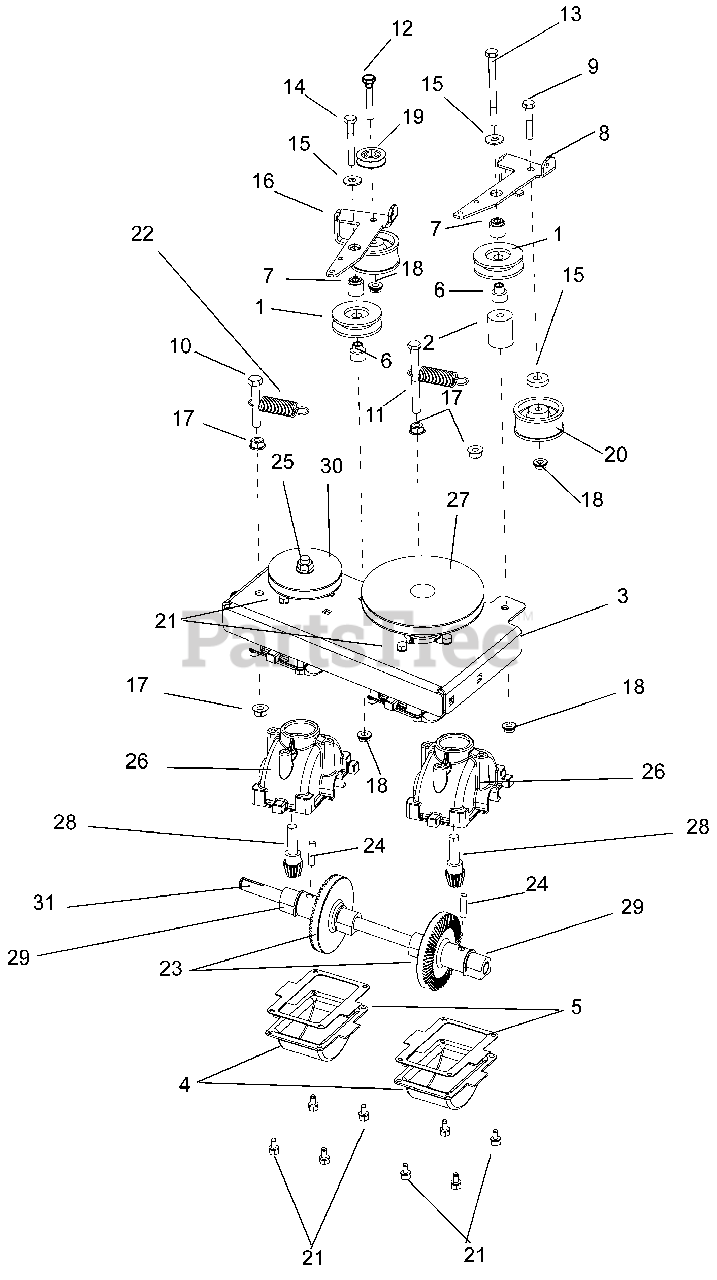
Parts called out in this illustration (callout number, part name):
1	Idler, 3L Front Side .38 x 1.875
2	Spacer, Reverse Idler
3	Plate, Transmission Mount
4	Sump, Gearbox
5	Gasket, Transmission
6	Spacer, Idler Pulley
7	Spacer .390 x .75 x .189
8	Bracket, Transmission Idler Arm
9	Bolt, Hex .25-20 x 1.50
10	Bolt, Hex .31-18 x 2.00
11	Bolt, Hex .31-18 x 3.50 Grade 5
12	Bolt, Hex .25-20 x 1.75
13	Bolt, Hex .25-20 x 3.25
14	Bolt, Hex .25-20 x 2.00
15	Washer, Flat Steel .312 x .734 x .065
16	Washer, Flat Steel .38 x .87 x .179
17	Nut, Spin Lock Flange .312-18
18	Nut, Locking Top Flange .25-20
19	Pulley, Cable
20	Pulley, Idler .25 x 1.87 x .97
21	Screw, Tapping 10-24 x .375 Pre-Coat
22	Spring, Tension .063 x .625 x 2.50
23	Gear, Bevel (CU Infiltrate)
24	Pin, .250 x 1.0 Spring
25	Nut, Top-Locking Flange .38-16
26	Housing, WAW Gearbox
27	Pulley, Reverse Input
28	Pinion, Gearbox Input
29	Bushing, Transmission Output Shaft
30	Pulley, Transmission Input
31	Kit, Shaft Service (Contains a new transmission shaft and two item 24 and eight item 21.)
32	Kit, WAW Transmission (Includes transmission shaft and items 3, 4, 5, 21, 23, 24, 25, 26, 27, 28, 29, 30)
